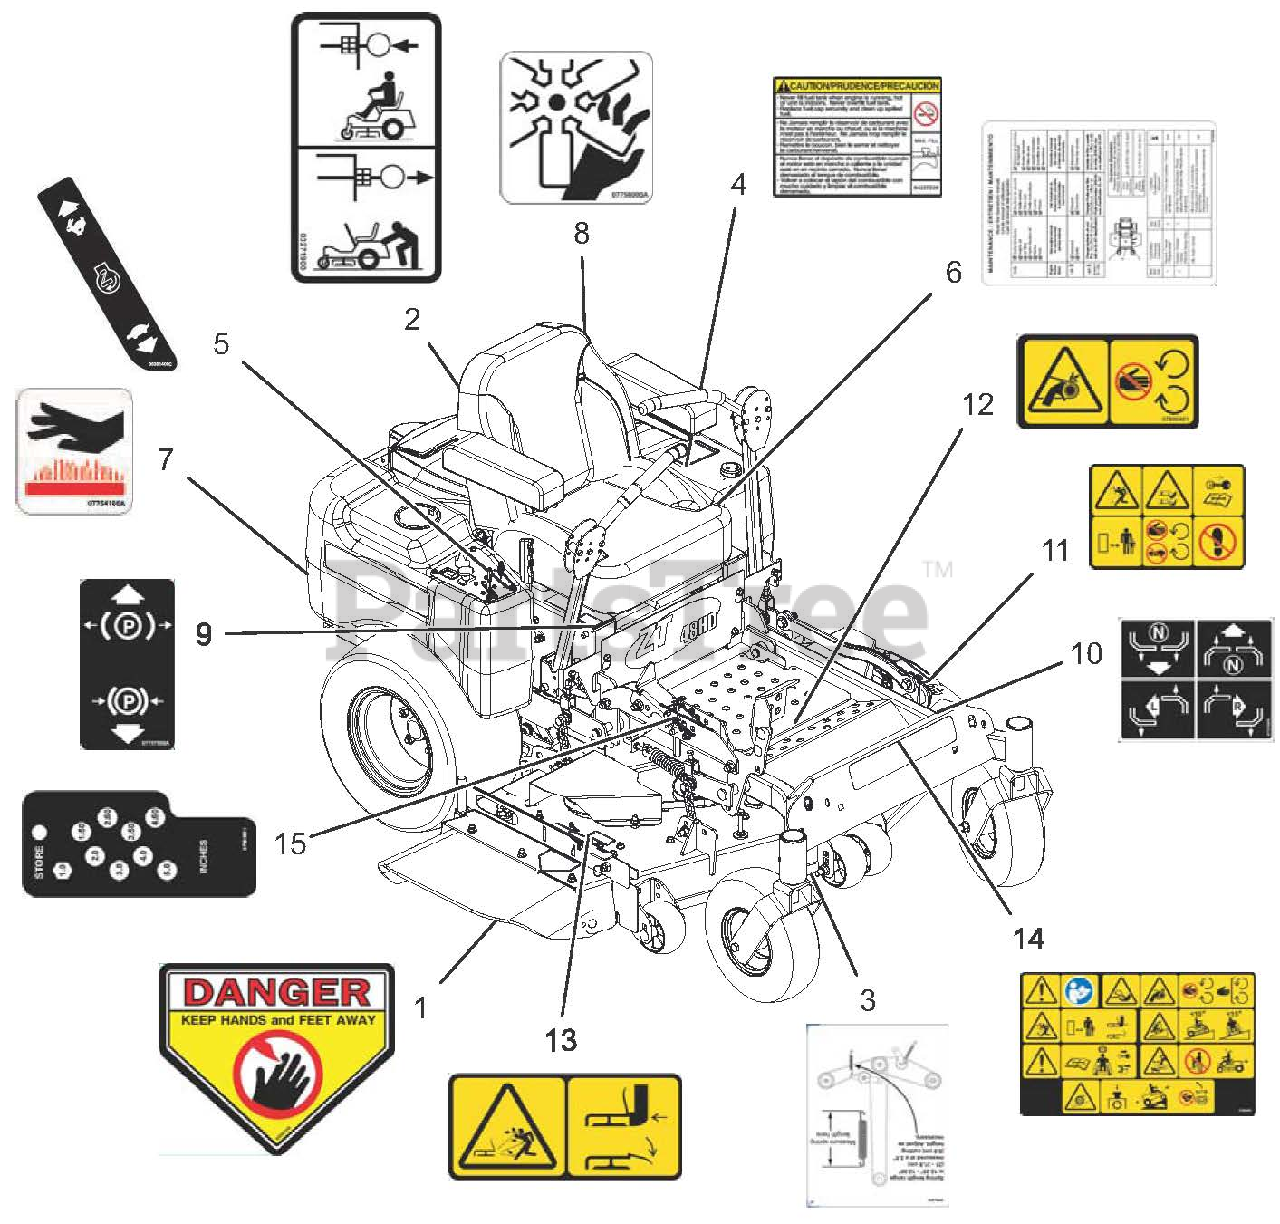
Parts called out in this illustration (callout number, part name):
1	DECAL, DANGER
2	DECAL, TRANSMISSION DISCONNECT
3	DECAL, BELT ROUTING
4	DECAL, FUEL WARNING
5	DECAL, SPEED CONTROL
6	DECAL, MAINTENANCE INSTRUCTIONS
7	DECAL, HOT SURFACE
8	DECAL, DANGER - FAN
9	DECAL, PARKING BRAKE LEVER
10	DECAL, INSTRUCTIONAL - STEERING
11	DECAL, SAFETY - MOWER DECK
12	DECAL, SAFETY - GUARDING
13	DECAL, SAFETY - DECK GUARDING
14	DECAL, MAIN SAFETY, COMMERCIAL
15	DECAL, HD HEIGHT OF CUT
